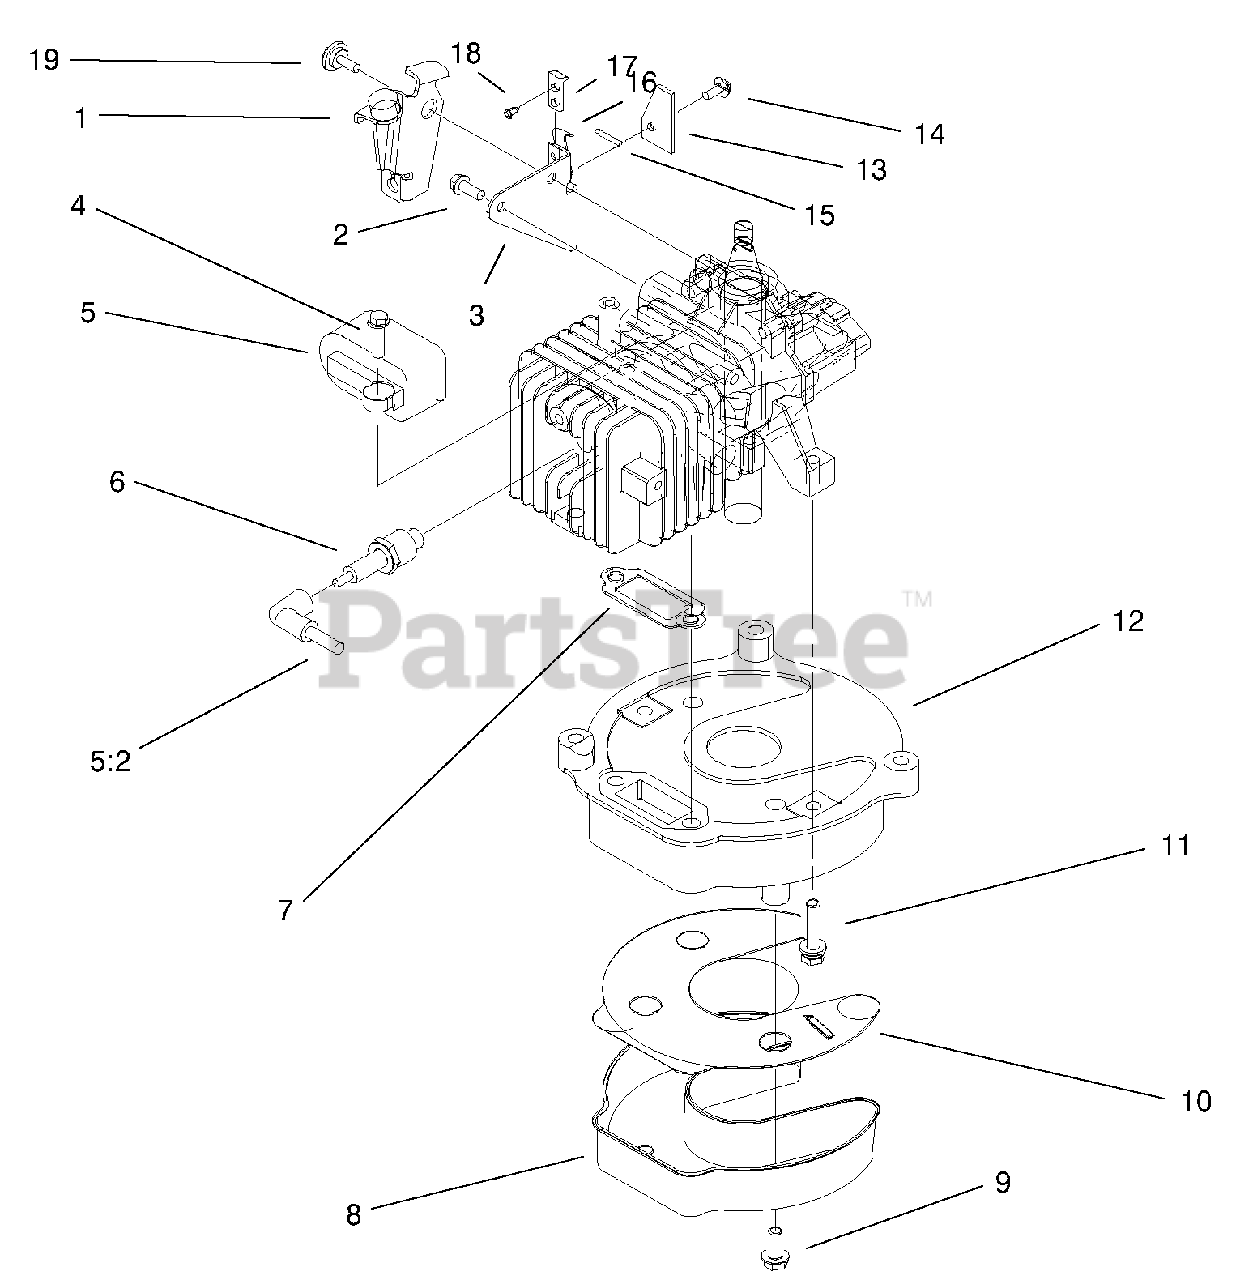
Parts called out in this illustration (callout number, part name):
1	Brake Plate ASM
2	Screw
3	Plate-Brake
5	Module-Ignition
5:2	Lead-Tension, High
6	Plug-Spark
7	Gasket-Exhaust
8	Cover-Muffler
10	Baffle-Muffler
12	Plate-Muffler
13	Stop-Strap, Ground
15	Electrical Lead ASM
16	Strap-Ground
17	Strap-Insulation
18	Rivet-Plastic
19	Screw-Shoulder
